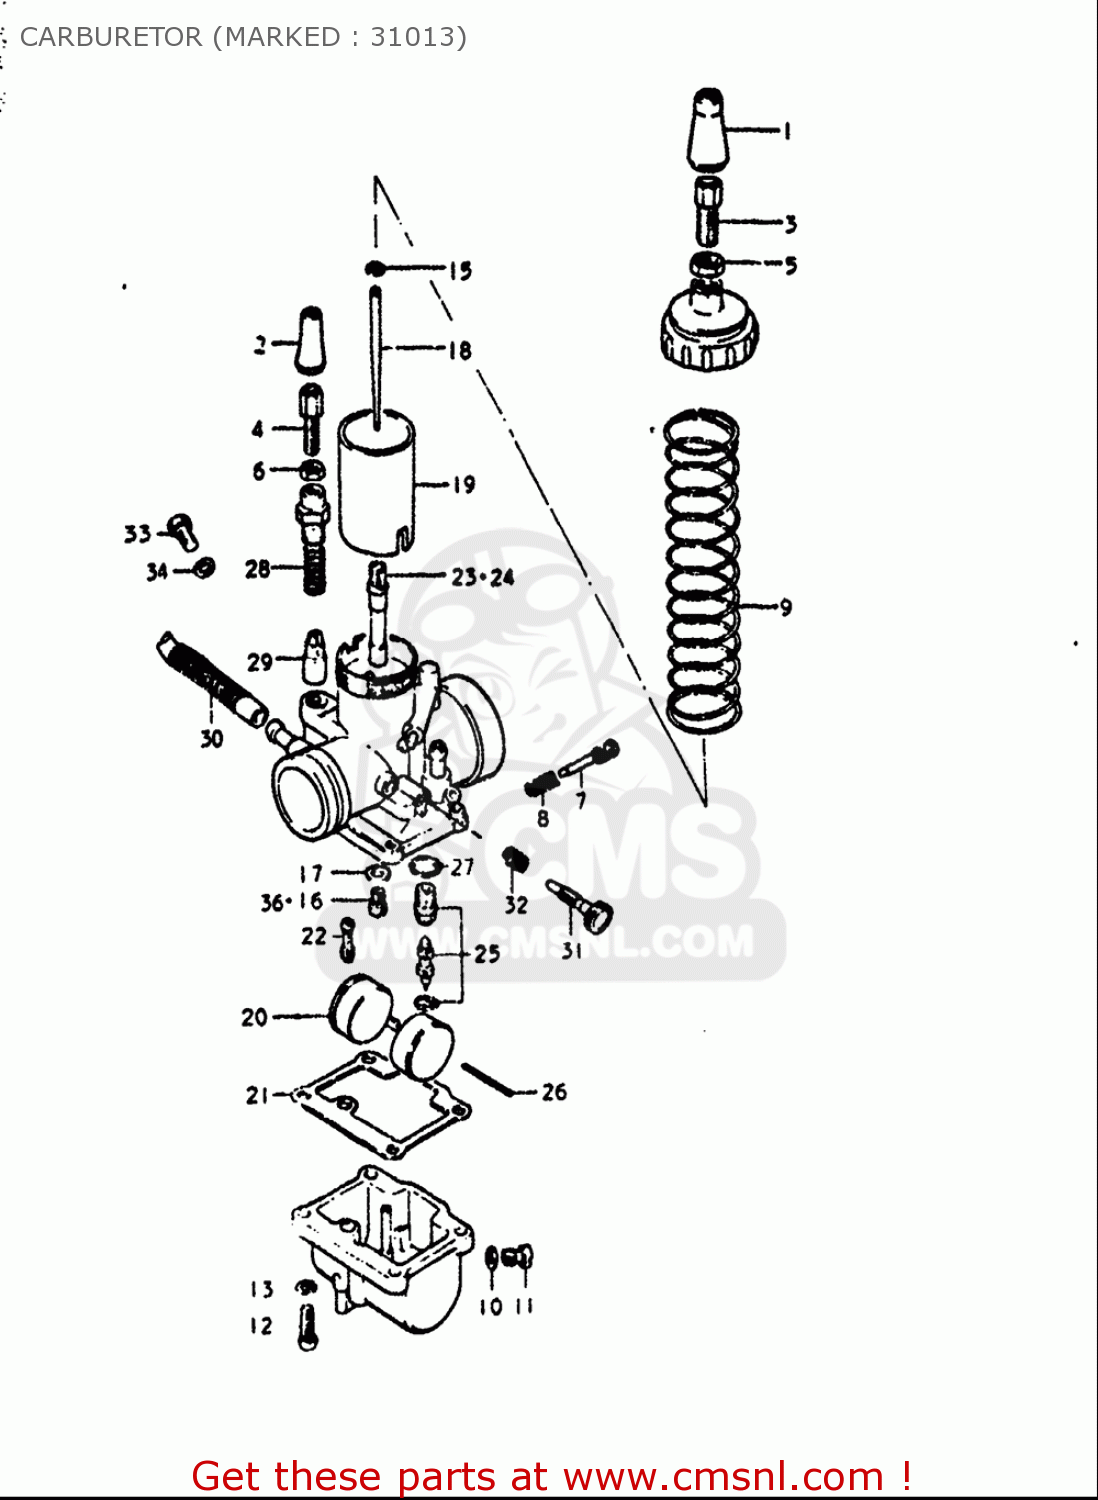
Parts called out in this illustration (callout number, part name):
2	CAP
4	ADJUSTER,CABLE
6	NUT
7	SCREW,PILOT AIR
8	SPRING
10	GASKET,DRAIN,PLUG (NAS)
11	PLUG
12	SCREW 4X16
13	WASHER,LOCK
15	CLIP
16	JET,MAIN
17	WASHER
20	FLOAT
21	GASKET,FLOAT CAHMBER (NAS)
22	JET,PILOT(30)
25	VALVE ASSY,NEEDLE
26	PIN,FLOAT
27	GASKET,MAIN JET HOLDER (NAS)
28	SPRING
29	PLUNGER,STARTER
32	SPRING,THROTTLE SCREW
33	BOLT
34	GASKET,THRO VALVE INSPECTION (NAS)
36	JET,MAIN(97.5)
37	JET,MAIN(105)
